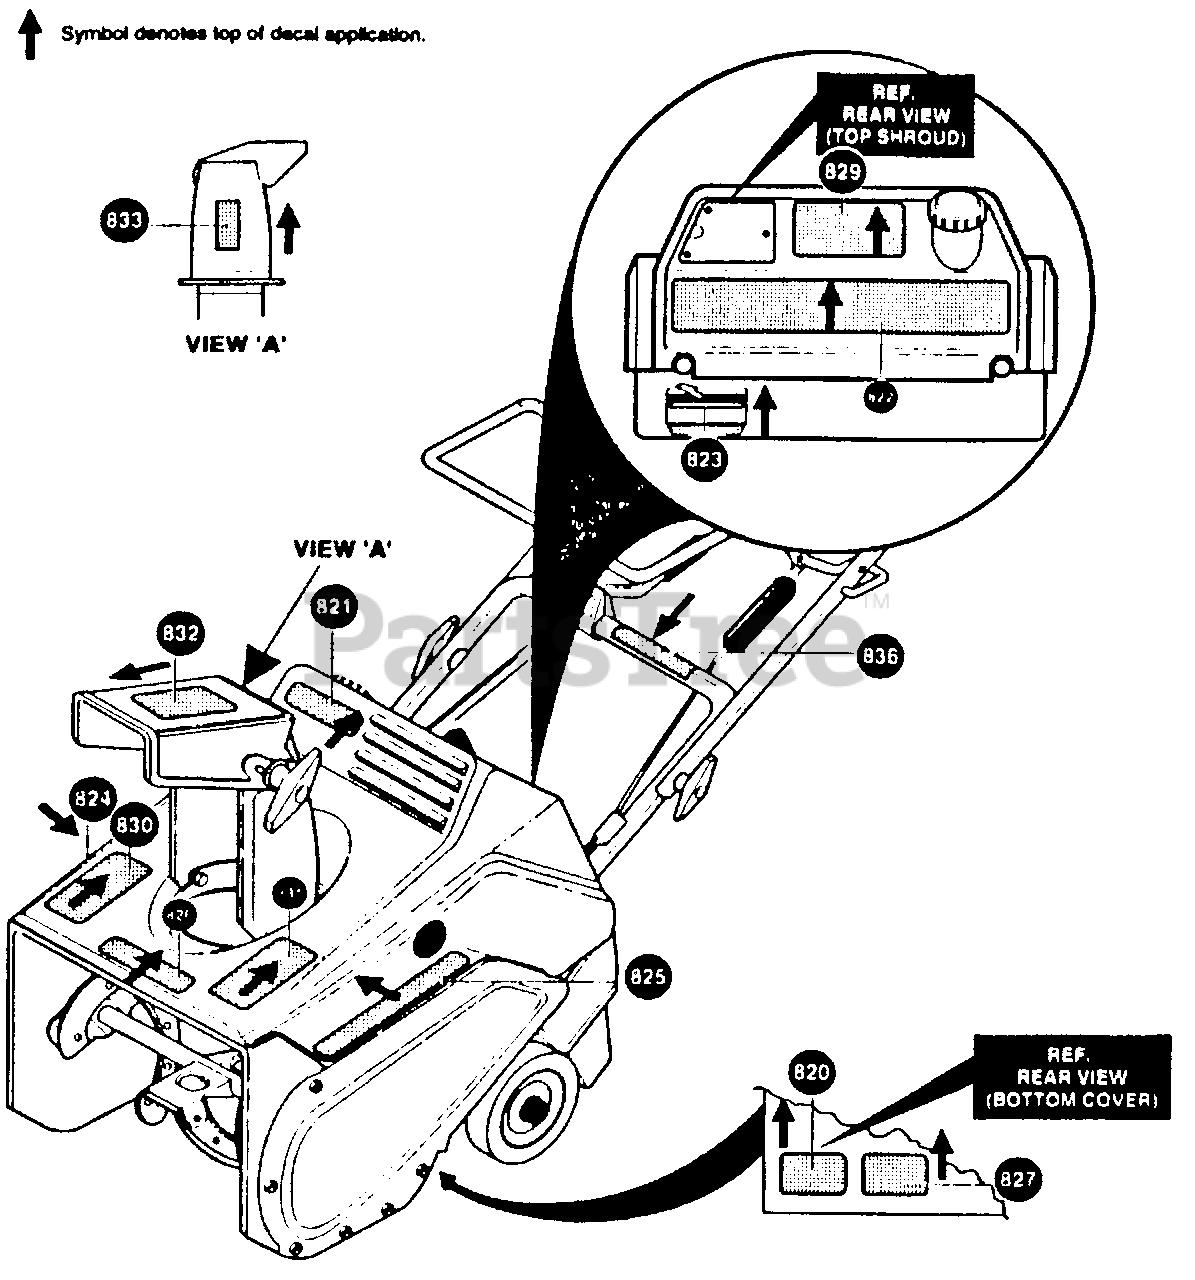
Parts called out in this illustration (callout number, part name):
821	DECAL, CROWN
822	DECAL, CONTROL PANEL
823	DECAL, CHOKE
824	DECAL, ST521M SIDE PANEL RH
825	DECAL, ST521E SIDE PANEL LH
826	DECAL, HUSQVARNA TOP COVER
827	DECAL, EPA
829	DECAL, START INSTR
830	DANGER CHUTE DECAL
831	DECAL, DANGER AUGER FOOT
832	DECAL, "CROWN" UPPRE CHT
833	DECAL, DANGER
836	DECAL, AUGER CONTROL BAR
